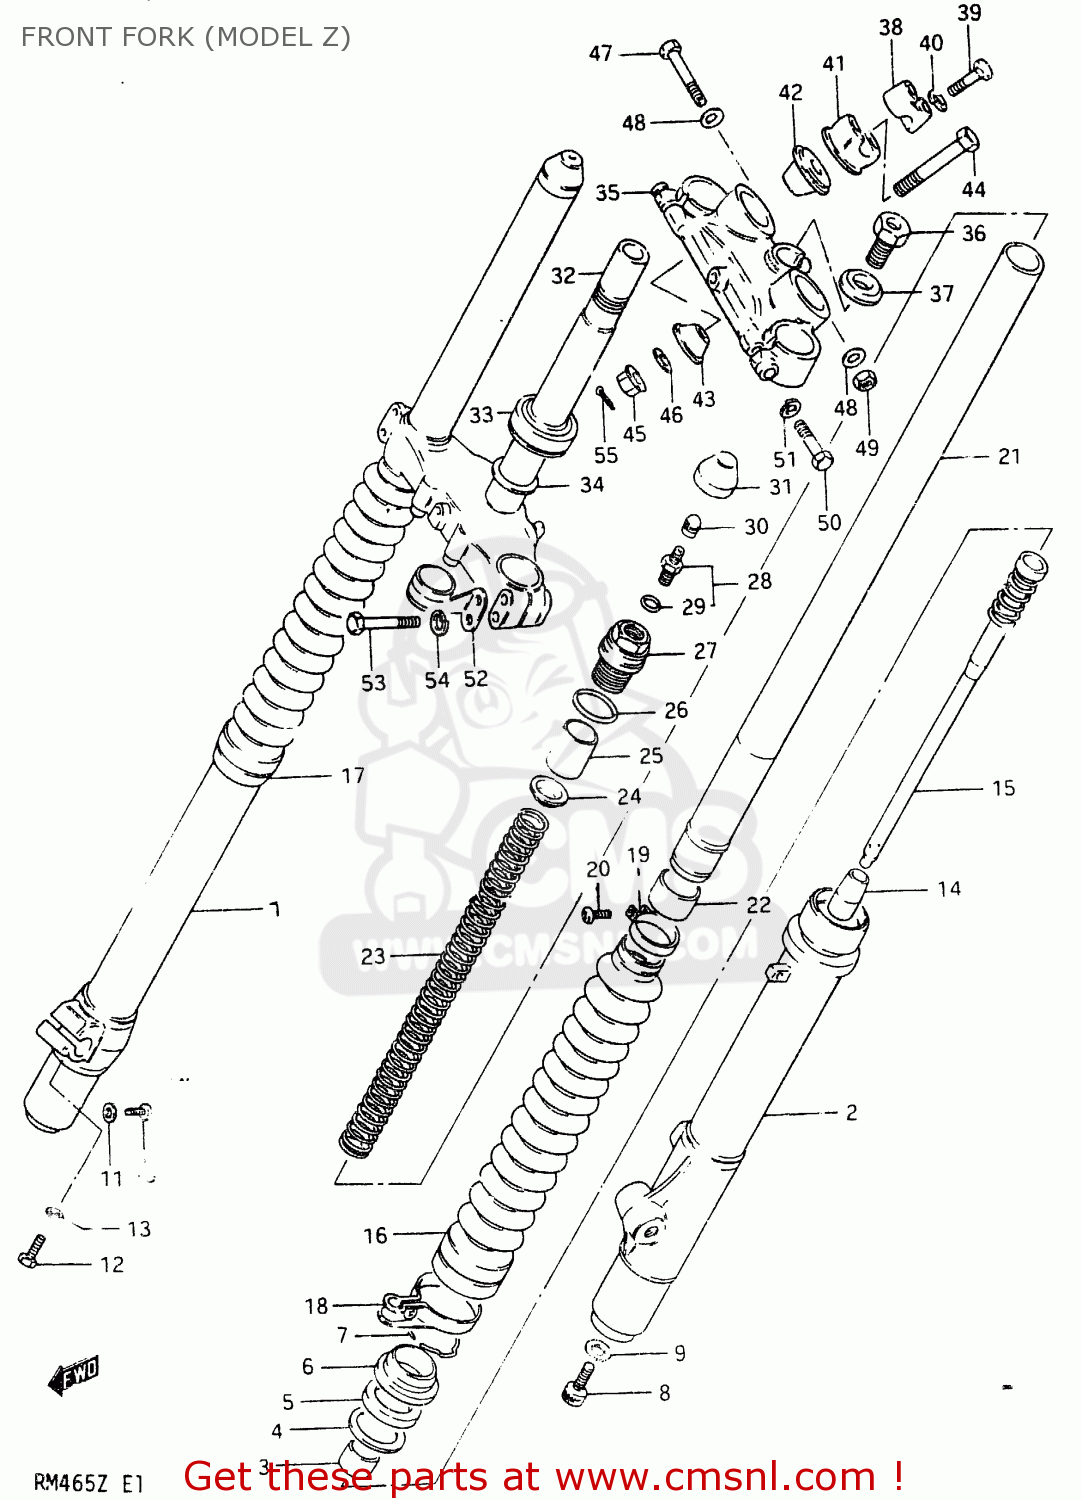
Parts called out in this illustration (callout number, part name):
1	TUBE,OUTER,RIGHT
2	TUBE,OUTER,LEFT
3	METAL,SLIDE
4	WASHER
5	OIL SEAL,FRONT FORK
6	DUST SEAL,FRONT FORK
7	RING,STOPPER
8	BOLT(14X25)
9	GASKET (NAS)
10	SCREW
11	GASKET,DRAIN,PLUG (NAS)
12	BOLT (8X30)
13	WASHER,LOCK,8.
14	PIECE,OIL LOCK
15	CYLINDER,FRONT FORK
16	BOOT,FRONT FORK COVER
17	BAND,FRONT FORK COVER
18	BAND,FRONT FORK COVER
19	BAND,FRONT FORK BOOT
20	SCREW 4X10
21	TUBE,FORK,INNER
22	PISTON
23	SPRING,FRONT FORK
24	GUIDE,SPRING
25	SPACER,FRONT FORK SPRING
26	O RING
27	CAP,FORK INNER TUBE
28	VALVE,FRONT FORK AIR
29	O-RING
30	CAP,VALVE AIR
31	CAP
32	STEM,STEERING
33	BEARING
34	WASHER,THRUST
35	HEAD,STEERING STEM
36	BOLT
37	WASHER
38	HOLDER,HANDLEBAR
39	BOLT
40	WASHER,LOCK,8.
41	HOLDER,HANDLEBAR
42	DAMPER,UPR
43	DAMPER,LWR
44	BOLT,HANDLE HOLDER
45	NUT
46	WASHER,HANDLEBAR HOLDER
47	BOLT 8X50
48	WASHER
49	NUT
50	BOLT
51	WASHER,LOCK,8.
52	GUIDE,CABLE
53	BOLT 8X40
54	WASHER,LOCK,8.
55	PIN 20X20
